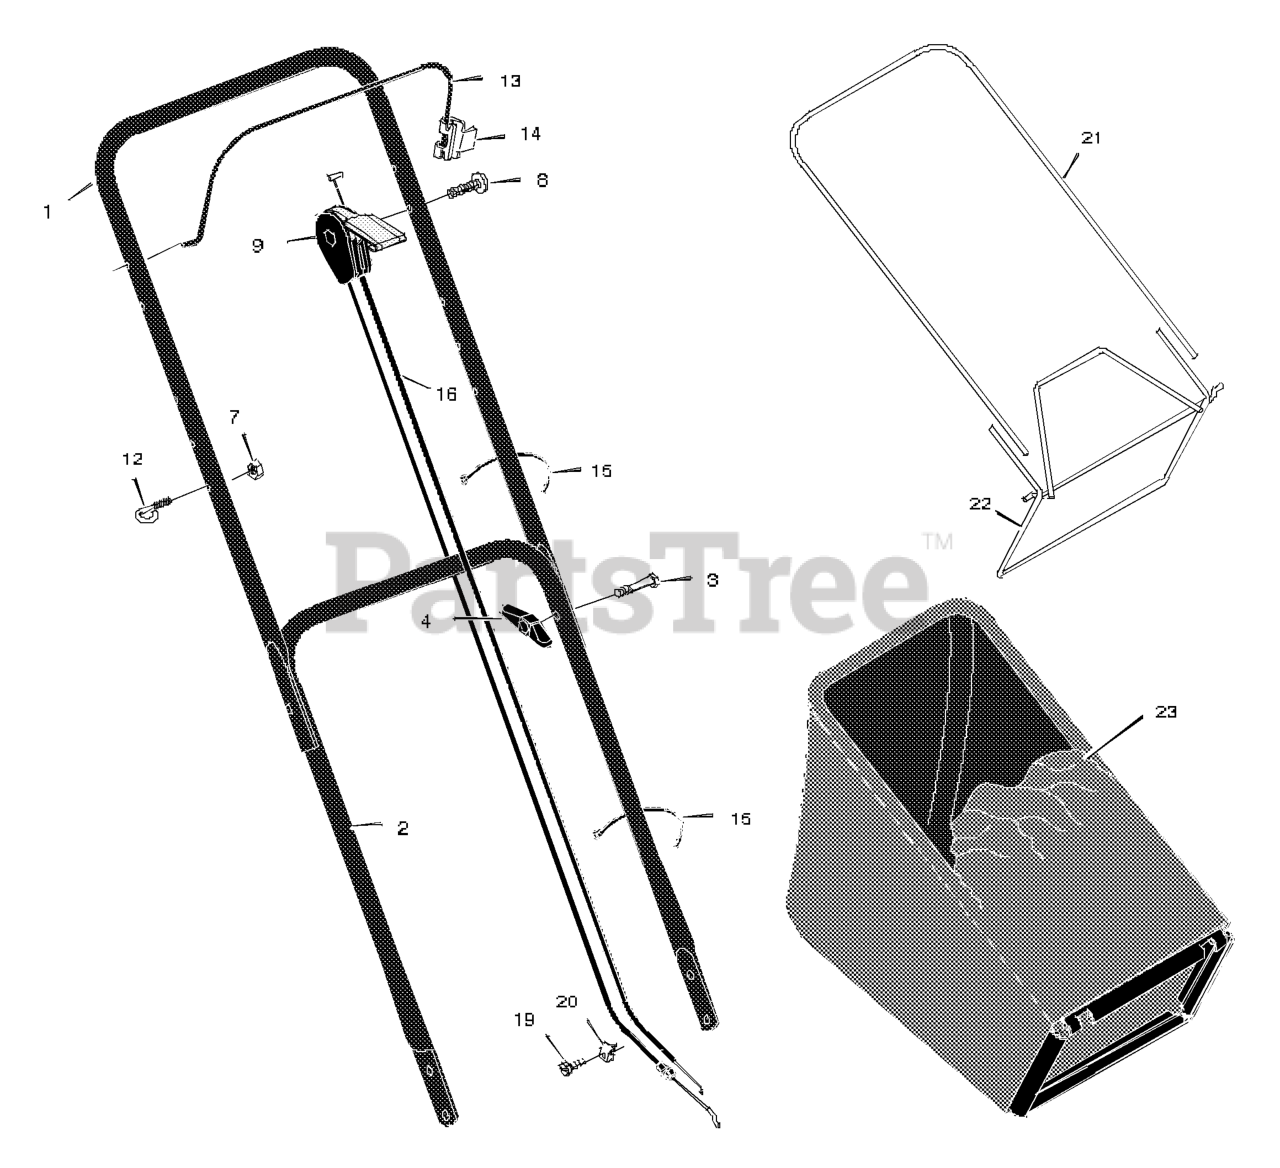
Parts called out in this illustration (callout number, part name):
1	Handle, Upper (Gray)
2	Handle, Lower (Gray)
4	Knob, Plastic
7	Locknut
9	Throttle Control
12	GUIDE, ROPE
13	Engine Stop Lever
14	Bracket, Stop Lever
15	Fastener, Cable
16	Engine Stop Cable
21	Frame, Top
22	Frame Assembly
23	Bag, Cloth
